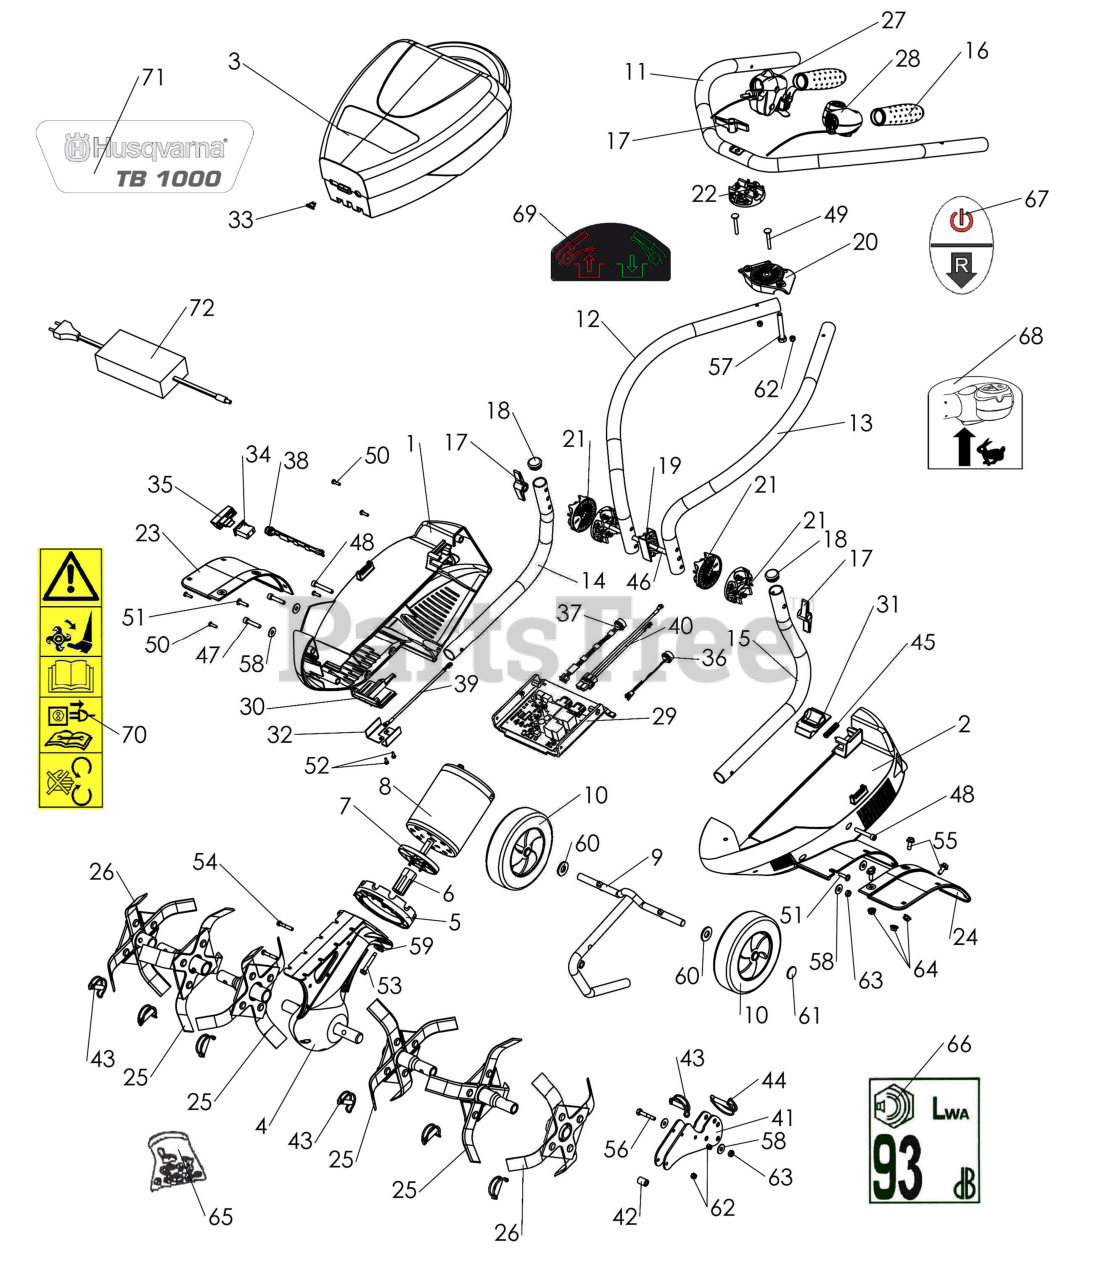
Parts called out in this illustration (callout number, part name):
1	Grey 627 right casing
2	Grey 627 left casing
3	Orange (RAL 2009) Battery pack
4	MBE transmission (1/18)
5	Engine/Transmission Adaptator
6	Engine hub
7	Fan Ø20
8	Engine 800W 36V
9	Wheel support + kickstand
10	Black Wheel Ø125 Ø8
11	Grey 627 top handlebar
12	Grey 627 right intermediate handlebar
13	Grey 627 left intermediate handlebar
14	Grey 627 right bottom handlebar
15	Grey 627 left bottom handlebar
16	Rubber hand side grip
17	Black handlebar tightening lever
18	Black plug Ø25
19	handlebar junction Ø25
20	inner handlebar junction
21	handlebar detent quadrant
22	handlebard detent quadrant with flat
23	Orange (RAL 2009) right protective fender
24	Orange (RAL 2009) left protective fender
25	Rotating blade 30x3 Ø240
26	Disk blade 30x3 Ø240
27	MBE right control
28	MBE left control
29	card + heat sink 800W
30	Thimbles support
31	Clip pack
32	Male Thimble V2
33	Fuse 40A
34	Fuse support MTA 03.00331
35	Cutout key
36	6 ways beam from card to casing
37	8 ways beam from card to casing
38	Charging beam plug
39	Positive plug cable from casing to security key
40	Positive battery beam from security key to card
41	Kickstand MBE V2 support
42	Spacer 6x12x17
43	Clip pin Ø8x32
44	Clip pin Ø8x45
45	Locking spring
46	Stud M8x175 / 30
47	Screw CHC M6x30z
48	Screw CHC M6x40z
49	Screw TBCC M z
50	Screw WN 1451 K 40x14 Trox
51	Screw WN5151 K50 x 16 z
52	Screw PT K 35x12 WM 1452 z
53	Self-tapping screw HM6x40 z (GC engine)
54	Screw HM 5x30z
55	Screw HM 6x16 z notched shoulder
56	Screw HM6x35z
57	Screw HM 8x55 z cl 10.9
58	Washer M6x18x1.2 Z
59	Washer 6.3x19x2.5 Z
60	Washer M 12x27x2.5 Z
61	Starlock washer Ø12
62	Blocking nut M5 Z
63	Blocking nut M 6 Z
64	Nut H M6 z notched shoulder
65	Bag of MBE screws
66	level noise label
67	On/Off/R label
68	Vmax label
69	Label "clutch lever"
70	Safety label
71	Husqvarna TB 1000 label
72	UL battery charger
